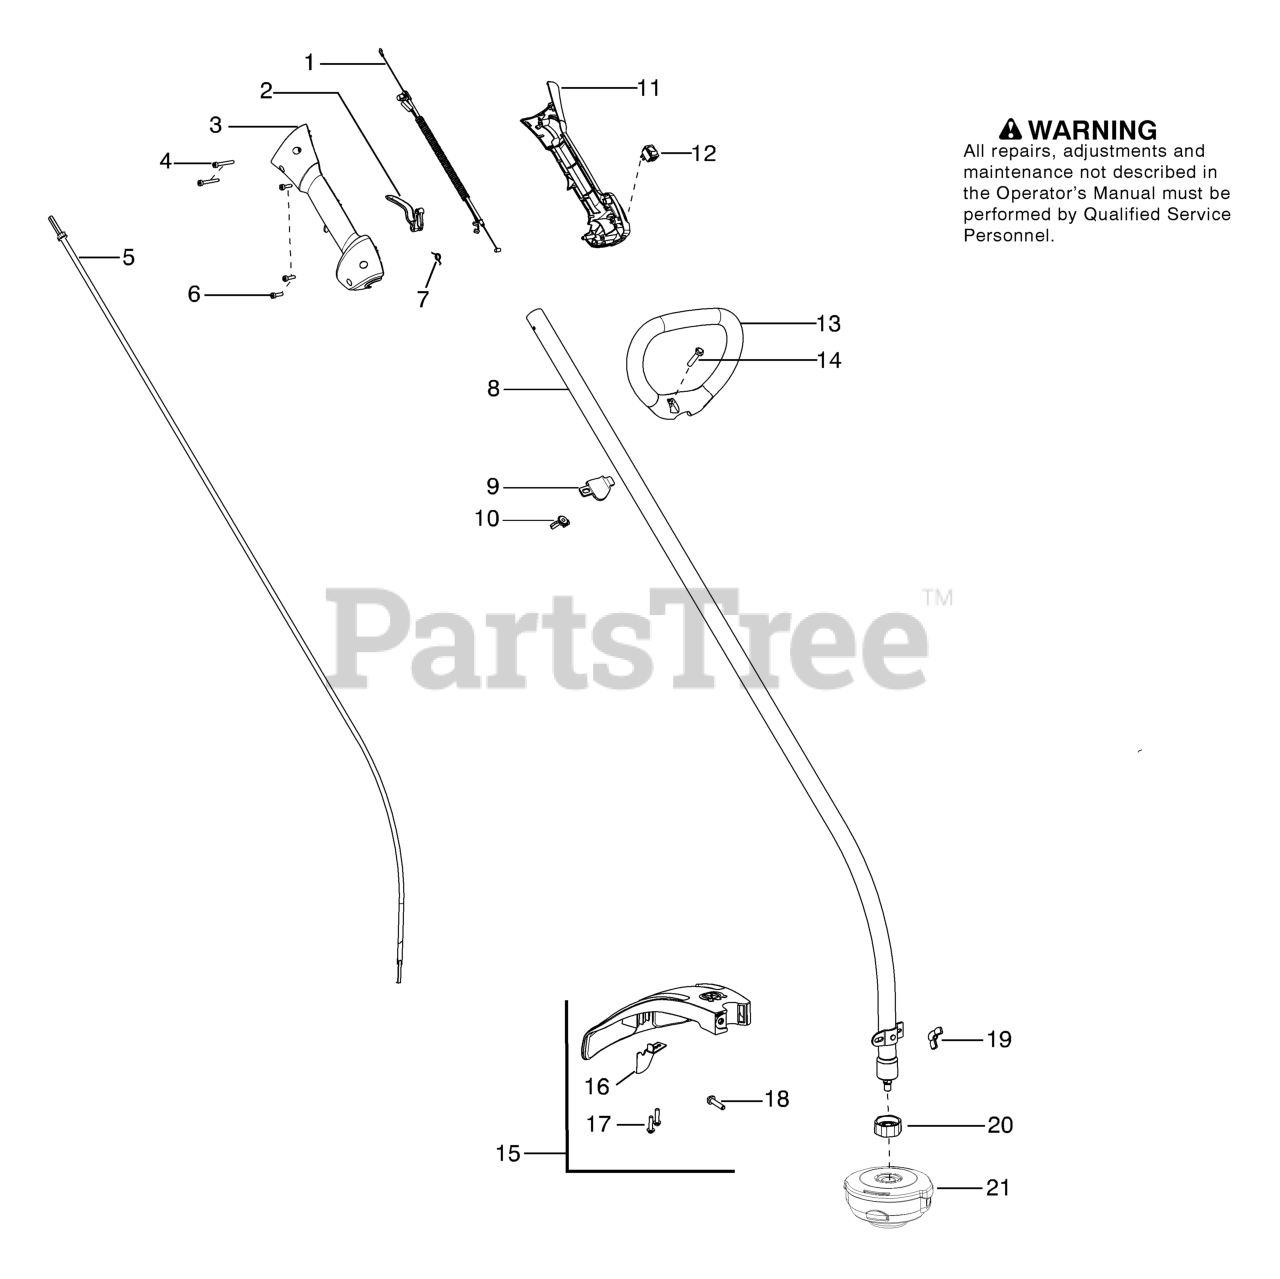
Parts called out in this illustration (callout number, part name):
1	%ASSY CABLE WIRE HARNESS
2	TRIGGER
3	HSG THROTTLE RH W/O SLOT
5	FLEX SHAFT 52"
6	SCREW M4 X 1.75 PT 16MM
7	SPRING TRIGGER
8	KIT DRIVESHAFT
9	CLAMP ASSIST HANDLE
10	WINGNUT, TYPE 2
11	THROTTLE HSG LH
12	KIT SWITCH
13	HANDLE ASSIST
14	BOLT, TYPE 2
15	TRIMMER GUARD 128C
18	BOLT, TYPE 2
19	WINGNUT, TYPE 2
20	ASSY- DUST CUP"C UNIT"
21	T25 TRIMMER HEAD 3/8 RH
